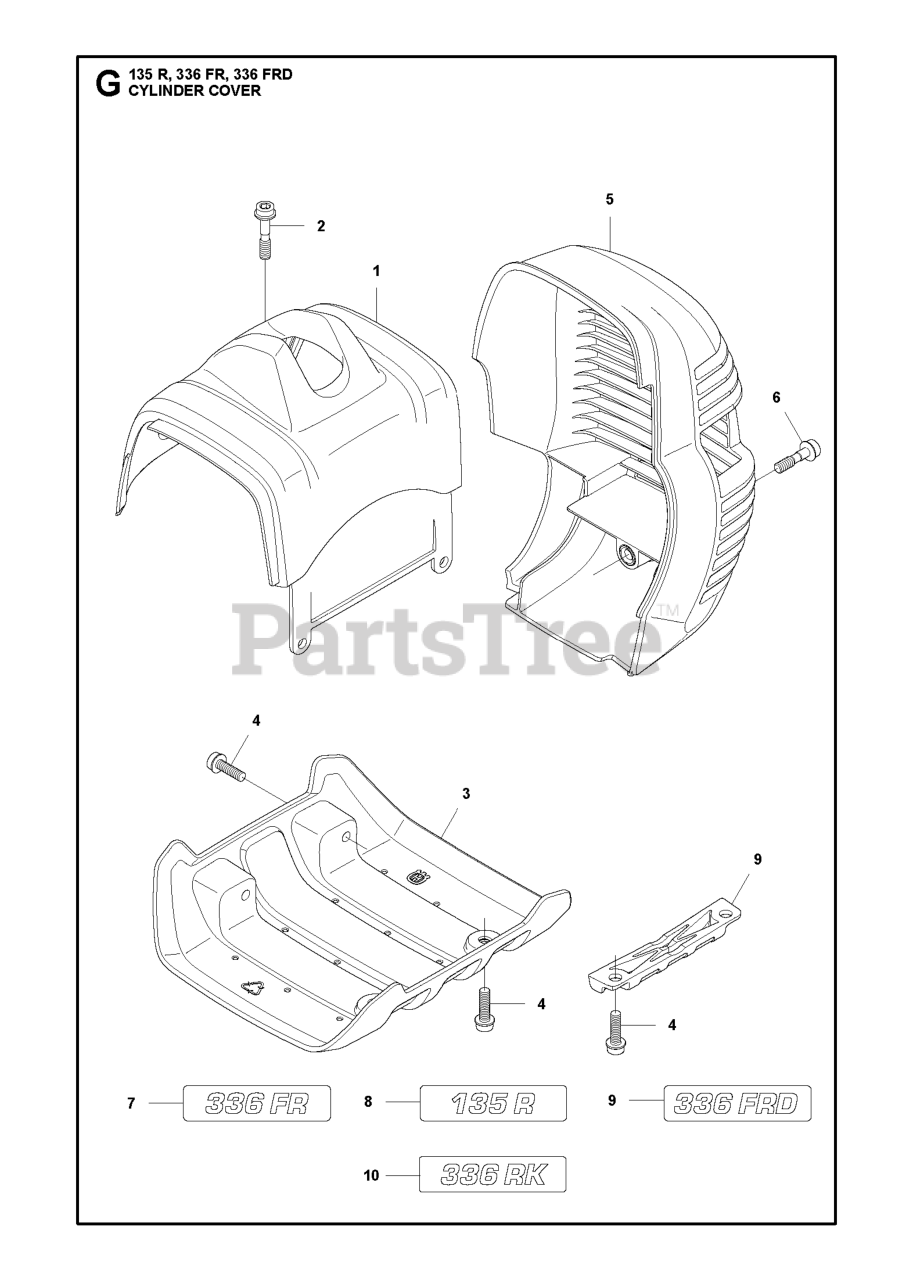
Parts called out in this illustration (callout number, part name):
1	CYLINDER COVER
2	SCREW IHSCFMO
3	PROTECTIVE PLATE
4	SCREW IHSCFM
5	MUFFLER GUARD
6	SCREW IHSCFMO
7	LABEL
8	LABEL
